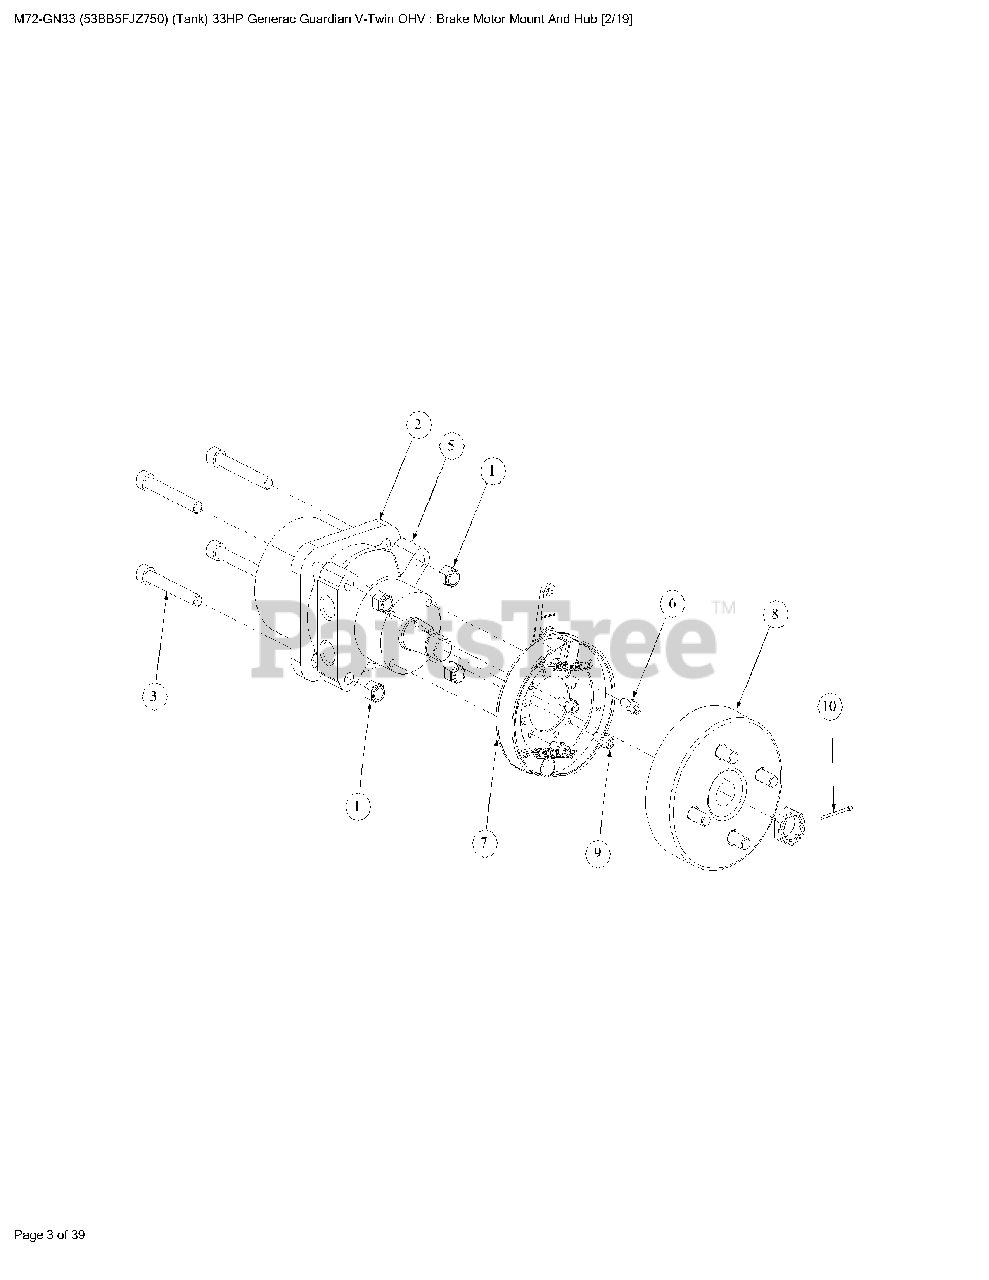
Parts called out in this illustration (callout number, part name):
1	Lock Nut, Nylon Insert, 1/2-13
2	Motor Spacer
3	Socket Head Capscrew, 1/2-13; 6-1/2
4	Hyd. Motor, Parker Left Hand Assembly w/Brake & Drum
5	Hyd. Motor, Parker Right Hand Assembly w/ Brake & Drum
6	Lock Washer, 5/16
7	Brake Assembly w/Line
8	Hub and Drum Assembly w/Studs
9	Capscrew w/Socket, 5/16-18 x 3/4
10	Cotter Pin 1/8 x 1-1/2
